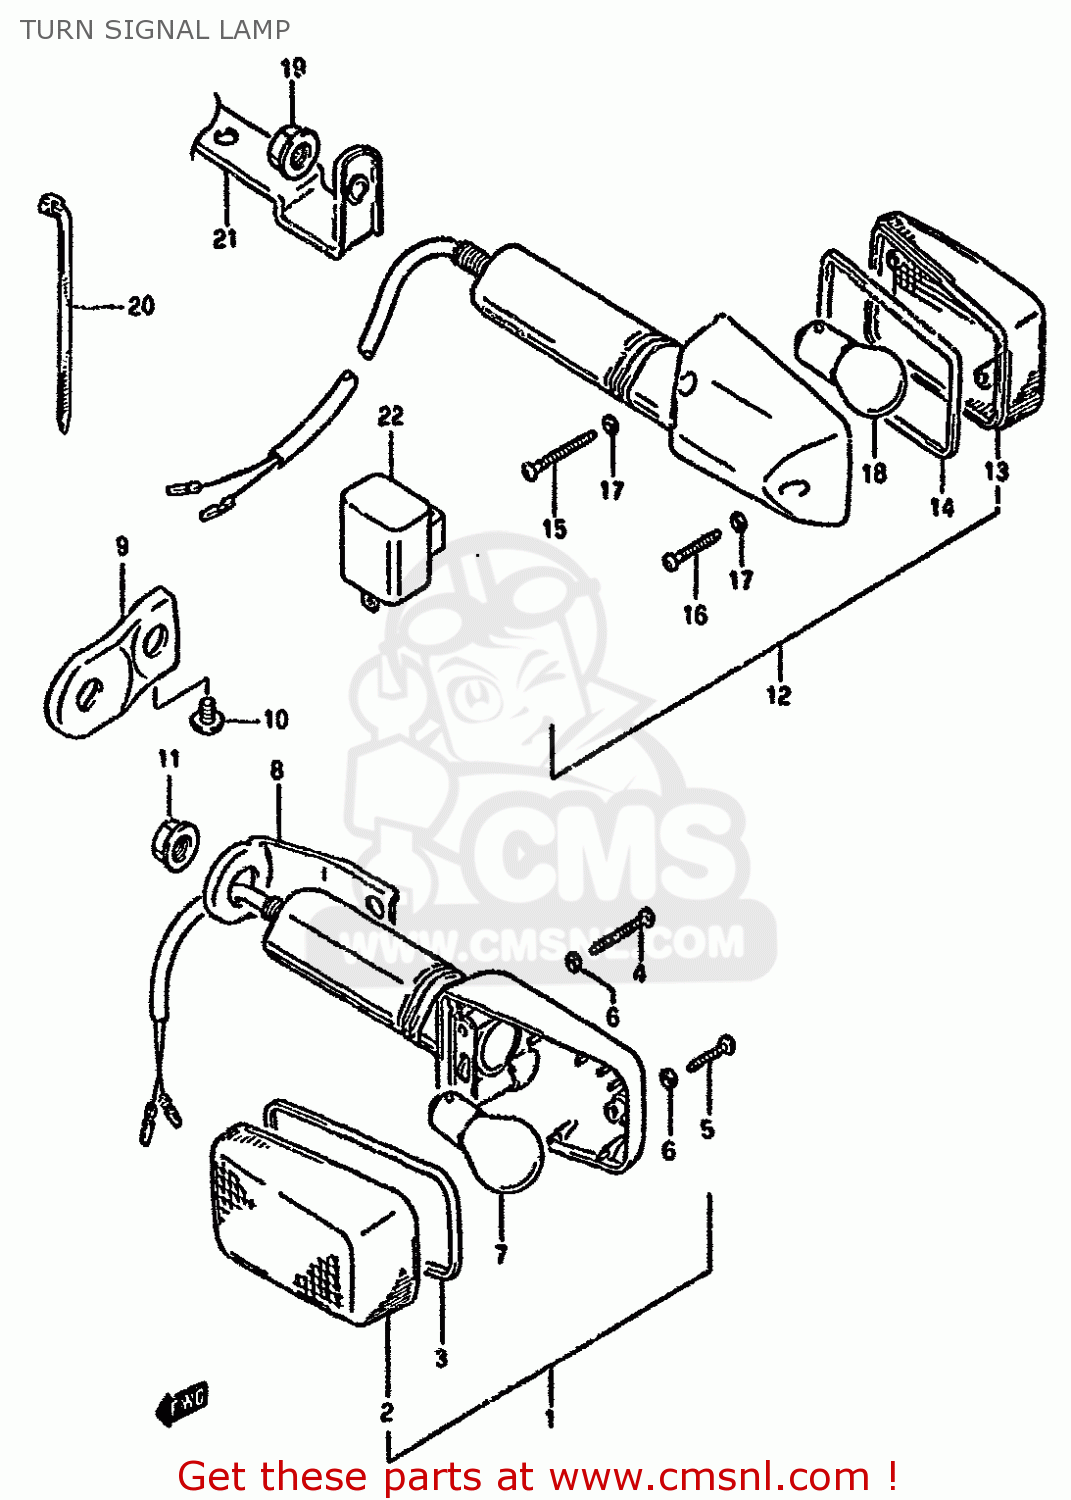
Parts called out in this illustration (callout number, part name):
1	LAMP ASSY,FR TURN SIGNAL
2	LENS
3	GASKET (NAS)
4	SCREW(3X30)
5	SCREW
6	GASKET (NAS)
7	BULB(12V21W)
8	BRACKET,FRONT TURN SIGNAL
9	BRACKET,FR TURN,R
10	SCREW
11	NUT
12	LAMP ASSY,RR TURNSIGNAL
13	LENS
14	GASKET (NAS)
15	SCREW(3X30)
16	SCREW
17	GASKET (NAS)
18	BULB(12V21W)
19	NUT
20	CLAMP
21	BRACKET,REAR TURN SIGNAL
22	RELAY ASSY,TUR
